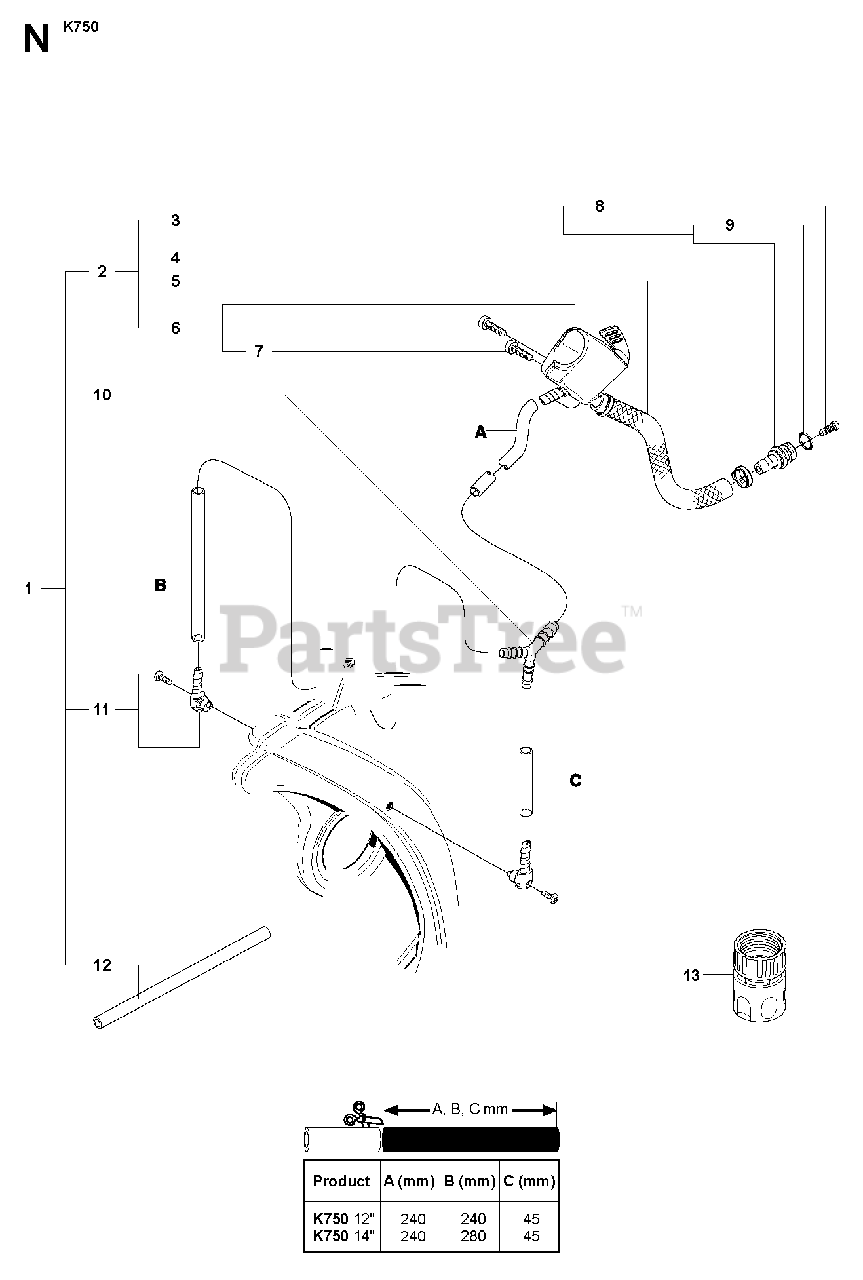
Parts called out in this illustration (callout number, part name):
1	HOSE KITIncl. 2, 10, 11, 12
2	HOSE ASSYIncl. 3, 4, 5, 6
3	NIPPLEIncl. 8, 9
4	HOSE CLAMP
5	HOSEL=230 mm
6	VALVE ASSYIncl. 7
7	SCREW ITXSCT
9	O-RING
12	HOSE800 mm
13	COUPLER
